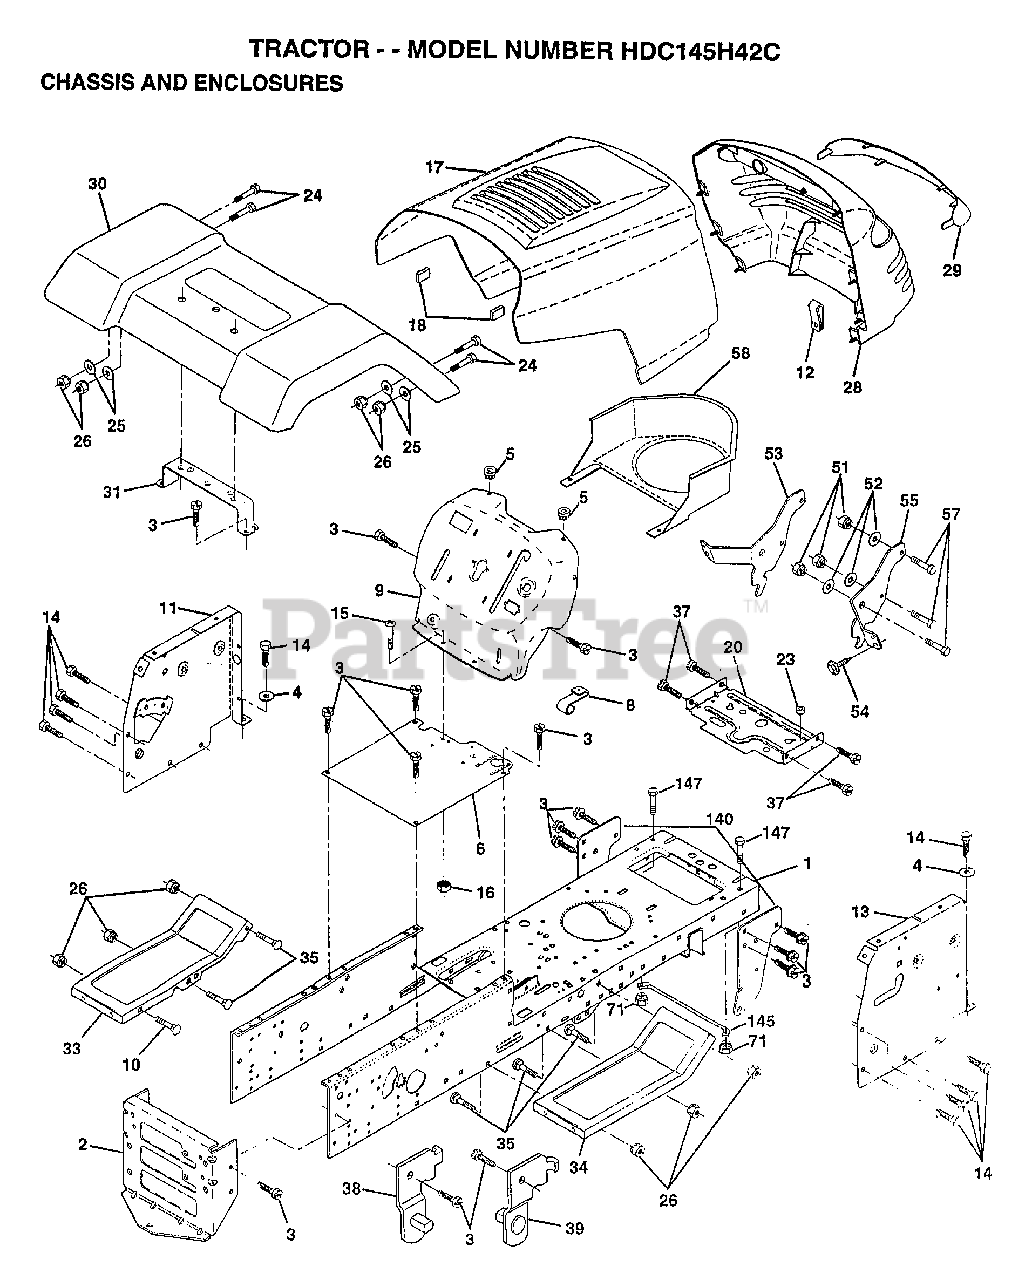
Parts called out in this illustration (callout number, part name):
1	CHASSIS ASM
3	SCREW
4	WASHER
5	BUMPER-HOOD/DASH
6	SADDLE
8	CLIP.RETAINER
9	DASH.SILKSCREENED
11	"PANEL-DASH,LH"
12	CLIP.TINNERMAN
14	SCREW LT
15	SCREW
20	"PLATE-MTG,BATT/FU"
24	BOLT
25	WASHER
26	NUT
28	GRILLE-MS428
29	LENS GRILLE
30	FENDER ASM LT W/S
31	BRKT FENDER
33	FOOTREST LH
34	FOOTREST RH
35	BOLT
37	SCREW LT
38	BRACKET ASM LH
39	BRACKET ASM RH
51	NUT
52	WASHER
53	BRACKET.GRILLE.LH
55	BRACKET.GRILLE.RH
58	AIR DUCT
140	BRKT SUSPENSION
145	"ROD POVOT,CHASSIS"
147	BOLT LT
